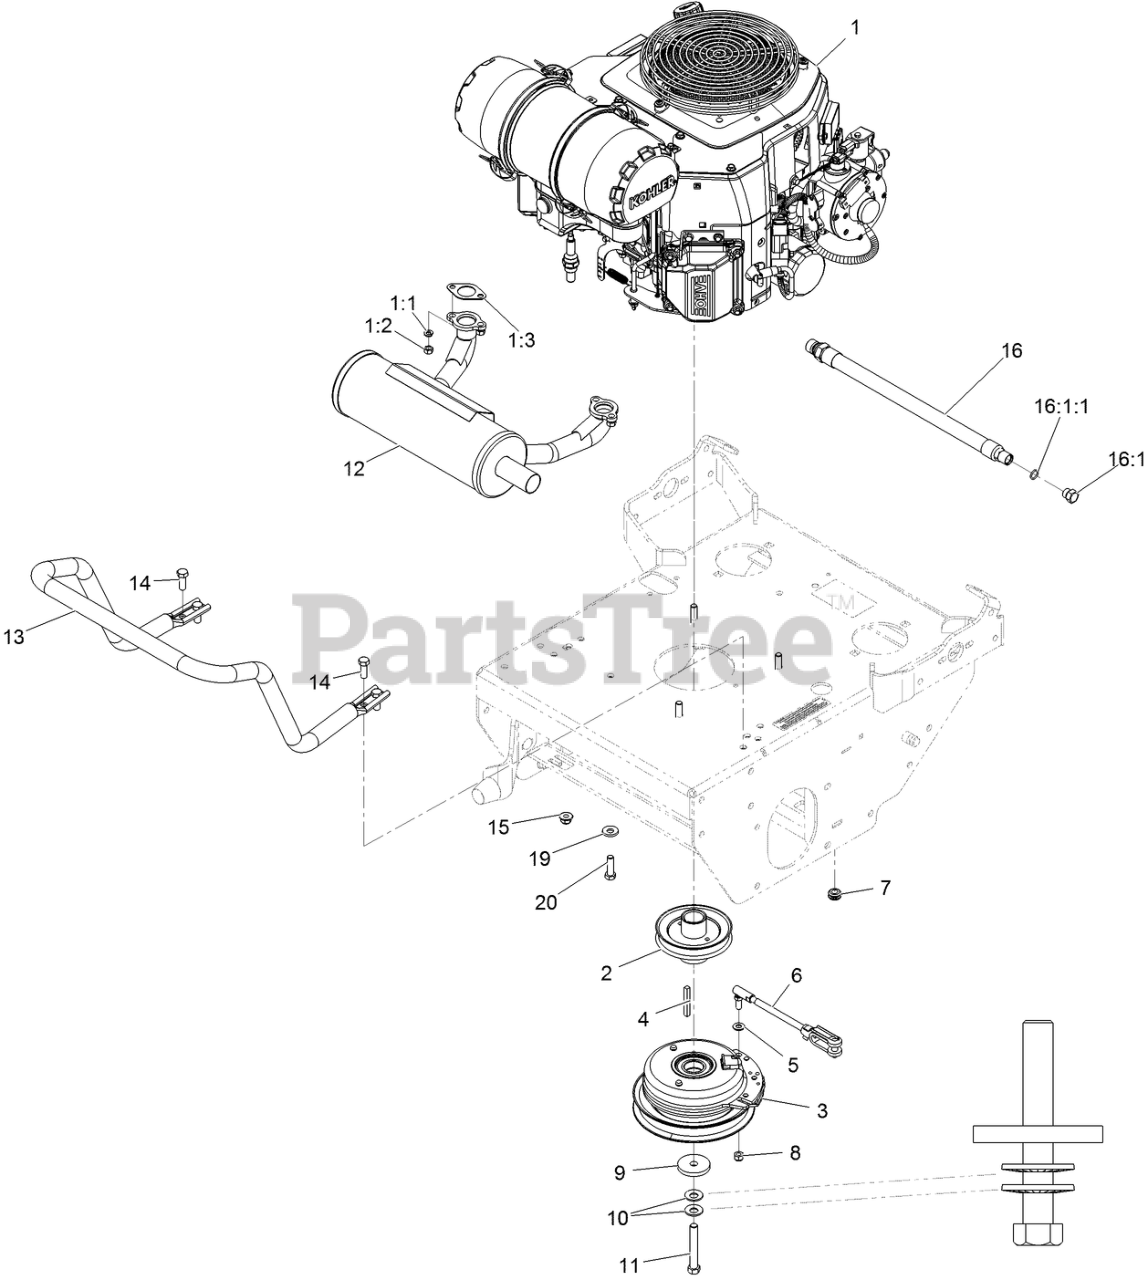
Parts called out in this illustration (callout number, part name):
1:1	WASHER-LOCK
1:3	GASKET-EXHAUST
2	SHEAVE, W/ HUB
3	CLUTCH, 105 FT/LBS, 1.13
4	KEY-SQUARE
5	WASHER-PLAIN
6	ASM, CLUTCH ANCHOR
7	GROMMET
8	NUT-LOCK
9	WASHER-CLUTCH
10	WASHER-SPRING
11	SCREW-HH
12	MUFFLER-HORIZONTAL
13	TUBE-GUARD MUFFLER
14	SCREW-HH
15	NUT-HF, NI
16	ASM, ENGINE OIL DRAIN HOS
16:1	PLUG-HH
16:1:1	O-RING
19	WASHER-BELLEVILLE
20	SCREW-HH
